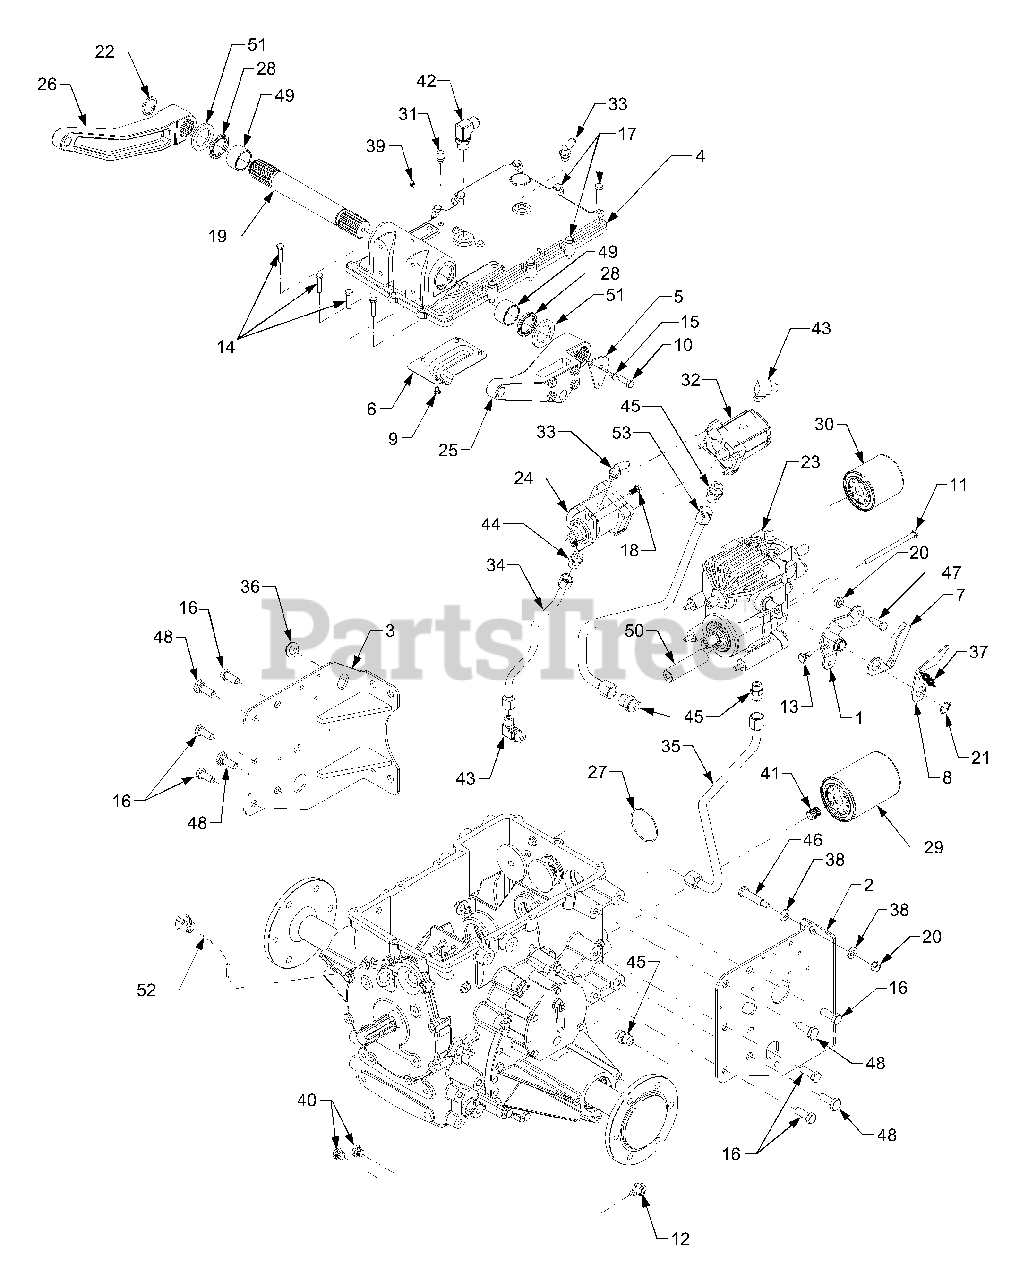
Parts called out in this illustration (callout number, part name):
1	Arm, Hydro Control
2	Bracket, Transmission Mtg. RH
3	Bracket, Transmission Mtg. RH
4	Cover, Transmission Housing
5	Plate, Feedback
6	Baffle, Oil
7	Arm, Neutral RH
8	Arm, Neutral LH
9	Screw, Hex Cap, 1/4-20 x .375 GR5
10	Screw, Hex Cap Lock, 3.8-24 x 1.0 GR5
11	Screw, Hex Cap, 5/16-18 x 5.25 GR5
12	Screw, Plug, M14 x 1.5 x .827
13	Screw, Hex Special Set, 5/16-18 x .625
14	Screw, Hex Cap, 3/8-16 x 1.25 GR5
15	Screw, Hex Cap, 1/4-20 x .5 GR5
16	Screw, Hex Cap, 1/2-13 x 1.25 GR5
17	Screw, Hex Cap Lock, 3/8-16 x 1.5 GR5
18	Screw, Low Hd. Cap, 3/8-16 x .75
19	Shaft, Rock
20	Nut, Hex Flange Lock, 3/8-16
21	Ring, Retaining
22	Ring, Retaining
23	Pump, Hydrostatic Transmission
24	Pump, Auxiliary Hydraulic
25	Arm, Upper Hitch RH
26	Arm, Upper Hitch LH
27	O-Ring, 2.987 ID x .103 Dia
28	Seal, Oil, 1.5 x 2.0 x .25
29	Filter, Oil, Hydraulic System
30	Filter, Oil
31	Breather, Transmission
32	Auxiliary Hydraulic Pump
32	Pin, Dowel
32	Bolt, Mounting
32	Coupler, Splined
33	Fitting, 90 degree
34	Tube, Auxiliary Pump Suction
35	Tube, Hydro Suction
37	Spring, Extension
38	Washer, Flat, .406 x 1.0 x .105
39	Fitting, Grease
40	Plug, Fitting
41	Fitting, Filter Nipple
42	Fitting, 90 degree
43	Fitting, 90 degree
44	Fitting, Straight
45	Fitting, Straight
46	Screw, Shoulder, .498 Dia x 1.45
47	Screw, Shoulder, .50 Dia x .685
48	Screw, Shoulder, .625 x .18: 1/2-13
49	Bearing, Sleeve, 1.52 x 1.75 x 1.0
50	Spacer, .40 x 1.0 x 3.9
51	Spacer, 1.52 x 2.25 x .188
53	Tube, Tandem Pump Suction
